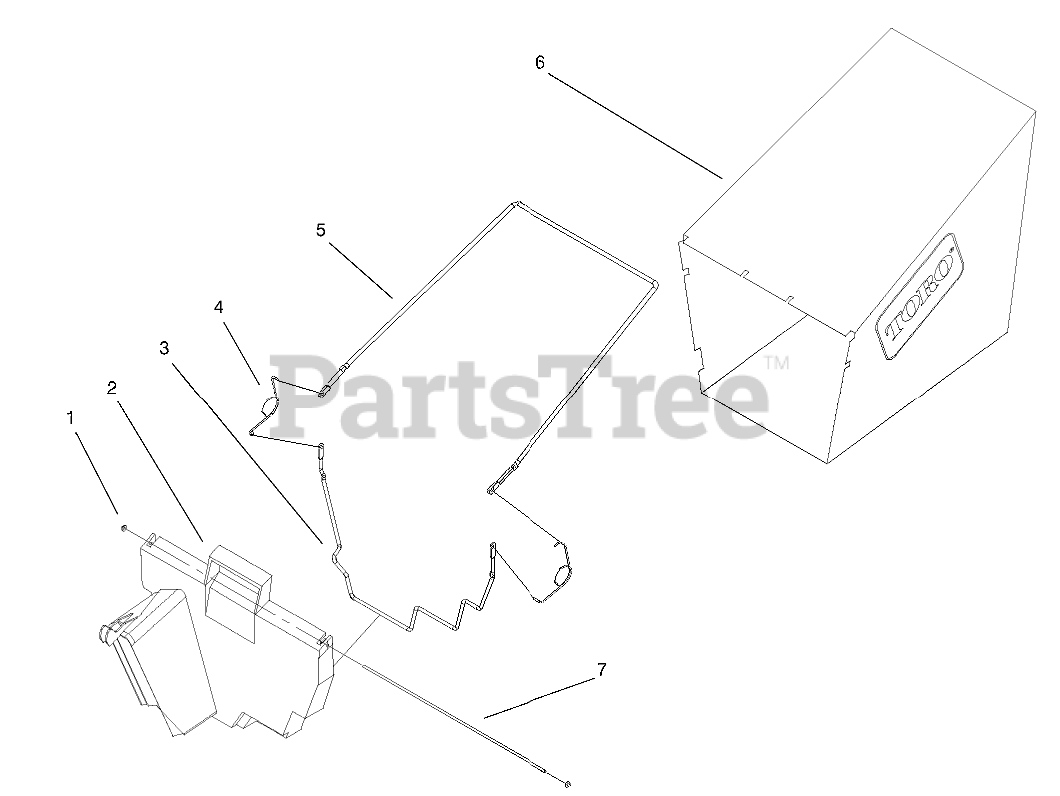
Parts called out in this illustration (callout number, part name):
1	Nut-Push (Only On: 20043)
2	Bag Door (Only On: 20043)
3	Frame-Bag (Only On: 20043)
4	Spring (Only On: 20043)
5	Frame-Upper Bag (Only On: 20043)
6	Grass Bag (Only On: 20043)
7	Hinge-bag Door (Only On: 20043)
